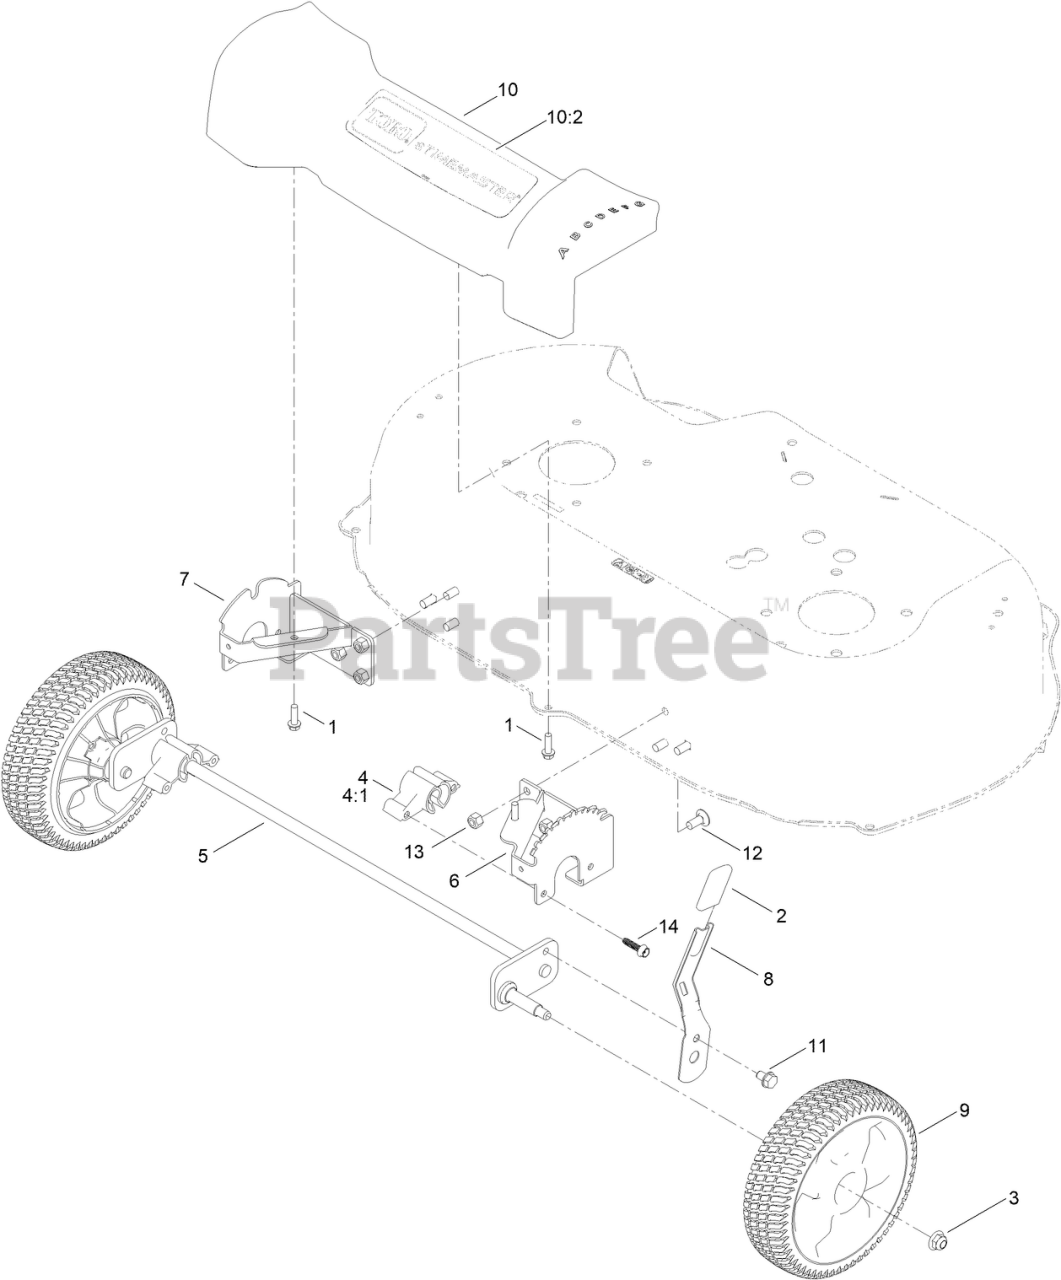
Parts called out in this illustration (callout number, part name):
1	SCREW-PLASTITE, HWH
2	GRIP-LEVER
3	NUT-HF, NI
4	BUSHING-PIVOT, FRONT
4:1	RESIN-NYLON 66
5	FRONT AXLE ASM
6	PLATE-HOC, LH
7	PLATE-HOC, RH
8	ARM-SPRING
9	8 INCH WHEEL ASM
10	FRONT COVER ASM
10:2	DECAL-COVER FRONT
11	SCREW-HWH, THD ROLL
12	BOLT-CARR
13	NUT-HEX
14	SCREW-FLANGE, PLASTIC
